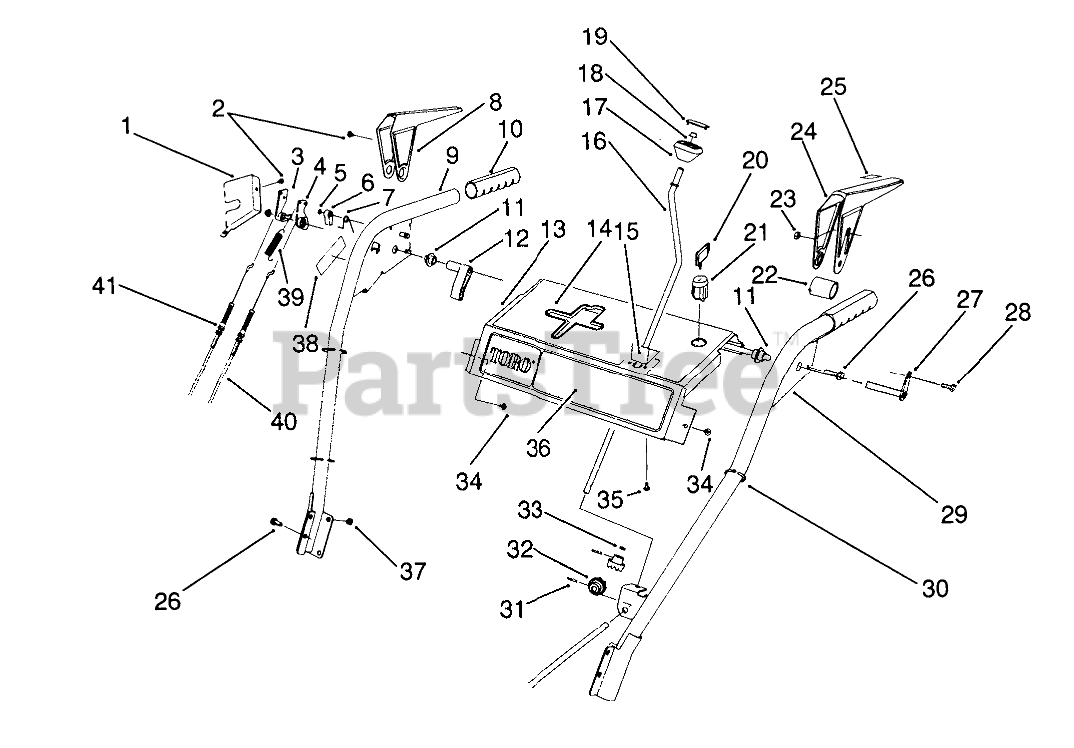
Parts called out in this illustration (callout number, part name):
1	Cover Lever Lock
2	SCREW-HH
3	TANG-LOCKING
4	CAM-RELEASE
5	E-RING-RETAINER
6	LATCH-LOCKING
7	SPRING-TORSION
8	Lever-Impeller
9	Handle-R.H.
10	GRIP-HANDLE
11	BUSHING-LEVER
12	LEVER-TRIP
13	Panel-Control
14	DECAL-TOP PANEL
15	PLATE-GUIDE
16	CRANK-ROD, CHUTE
17	KNOB-CONTROL, CHUTE
18	RETAINER-PUSH ON
19	COVER-KNOB
20	KEY-IGNITION
21	SWITCH
22	SPACER-LEVER, TRACTION
23	NUT-LOCK, NI
24	Lever-Traction
25	DECAL-LEVER
26	SCREW-HHF
27	CROSS ROD ASM
28	SCREW-HWH
29	Handle-L.H.
30	TIE-CABLE
31	PIN-SPRING
32	GEAR-UNIVERSAL
33	WASHER-RUBBER
34	SCREW-HWHTF
35	SCREW-PPH
36	DECAL-FRONT PANEL (828)
37	NUT-LOCK, NI
38	DECAL-WARNING
39	Spring-Extension
40	CABLE-TRACTION
41	CABLE-IMPELLER
